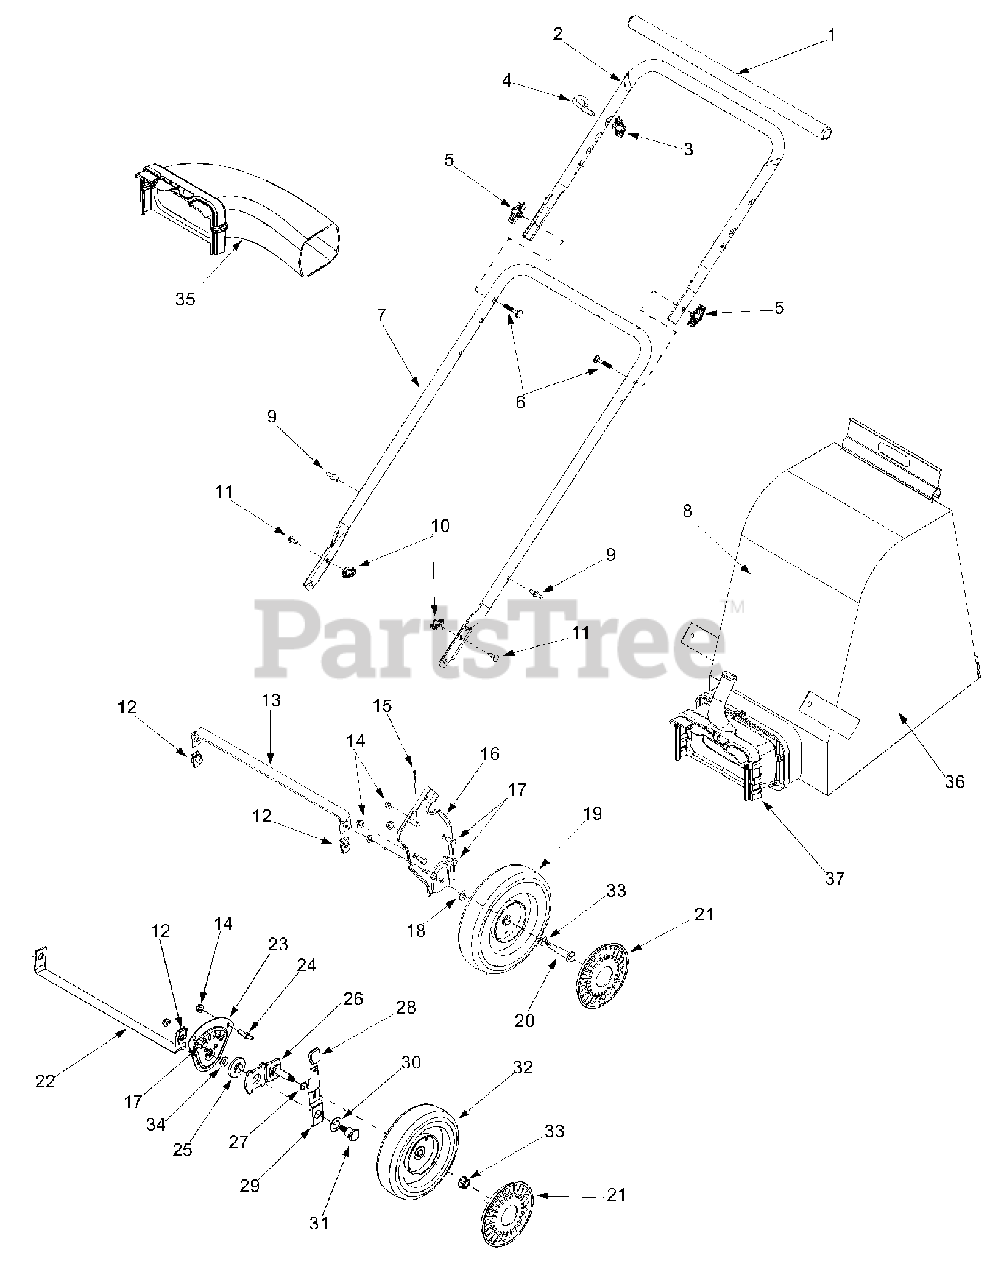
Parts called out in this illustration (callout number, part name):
1	Foam Grip
4	Eye Bolt
5	Handle Knob 5/16-18
6	Carriage Bolt
8	Bag Assembly
9	Studs
10	Wing Nut 1/4-20
11	Carriage Screw 1/4-20 x .75
12	Lock U-Clip Nut 3/8-16
15	Cotter Pin
17	Hex Cap Screw 5/16-18 x .625
18	Bell Washer.401 ID x.870 OD
19	Wheel 9 x 2
20	Shoulder Screw 3/8-16
21	Hubcap
25	Height Adjustment Bearing
26	Pivot Arm Assembly
27	Wave Washer .531 ID x .781 OD
28	Height Adjustment Knob
29	Spring Lever
30	Bell Washer .760 ID x .25OD
31	Shoulder Screw .750 ID x .625 OD
32	Wheel 8 x 2
33	Flange Lock Nut 3/8-16
34	Thrust Washer .375 ID x .70 OD
35	Blower Chute Assembly
36	Bag
37	Chute Assembly
